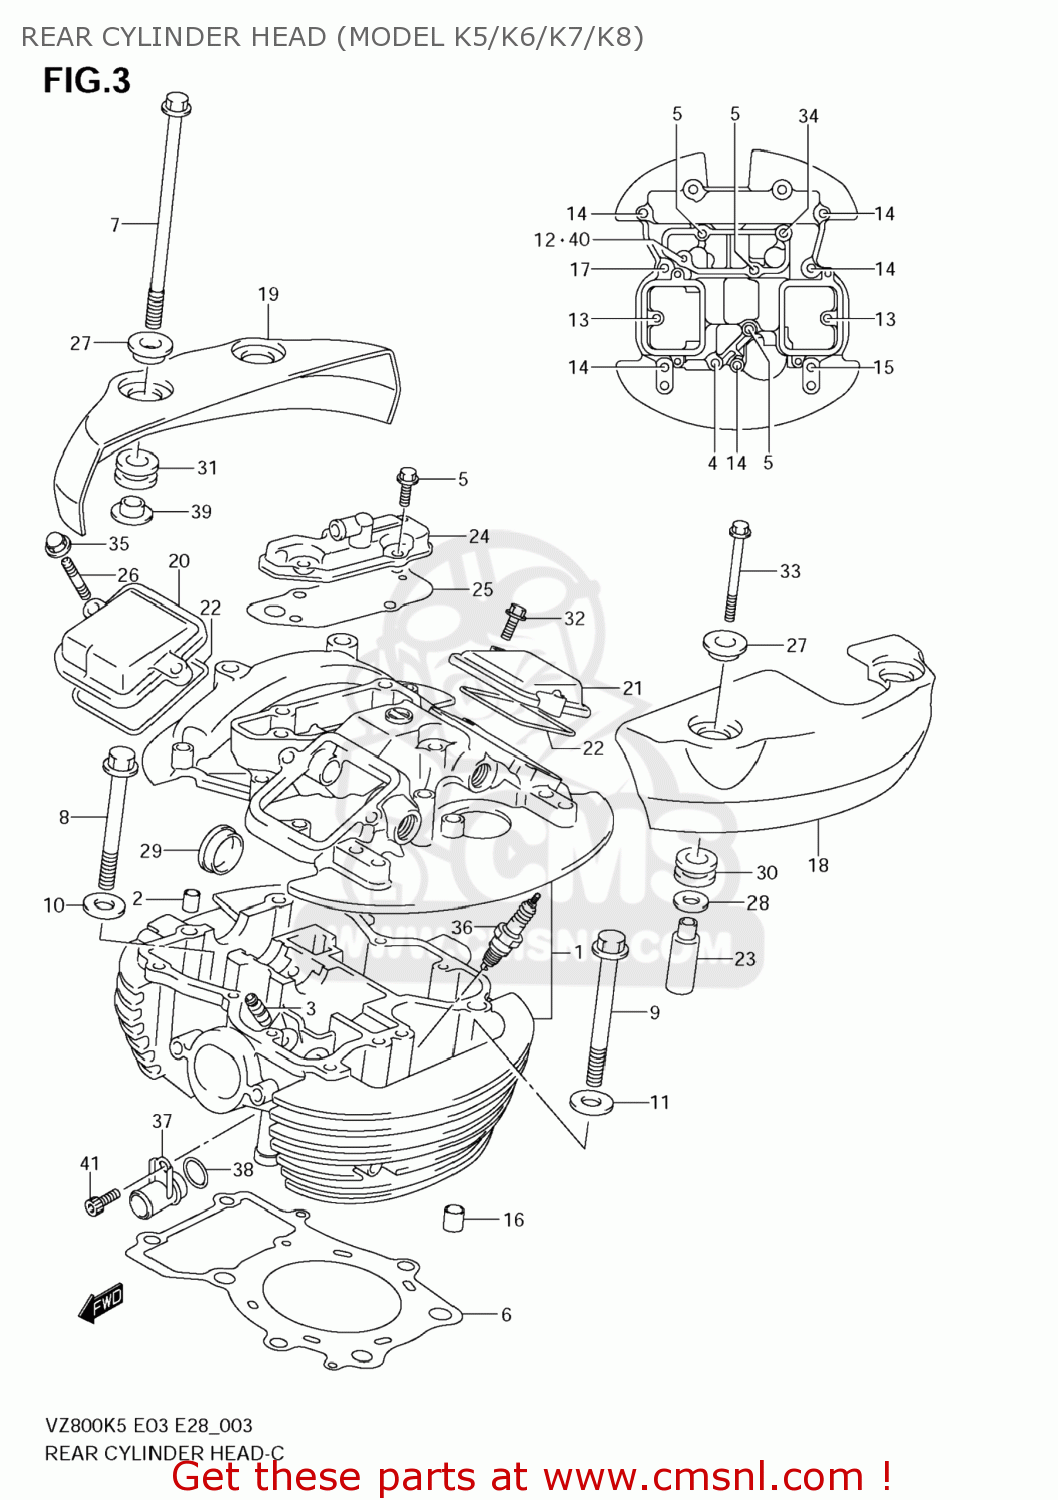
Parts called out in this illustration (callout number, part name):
1	HEAD ASSY,CYLINDER RR
2	PIN(8.4X11X14)
3	GUIDE,VALVE
4	BOLT(6X50)
5	BOLT(6X55)
6	GASKET,CYLINDER HEAD RR (NAS)
7	BOLT(8X250)
8	BOLT(10X155)
9	BOLT(10X165)
10	WASHER(8.5X24X1.6)
11	WASHER(10.5X22X2.3)
12	BOLT(6X55)
13	BOLT
14	BOLT
15	BOLT
16	PIN
17	BOLT
18	CAP,CYLINDER HEAD COVER RR,L
19	CAP,CYLINDER HEAD COVER RR
20	CAP,INSPECTION INTAKE
21	CAP,INSPECTION EXHAUST
22	GASKET,INSPECTION CAP (NAS)
23	SPACER,CYL HEAD COVER CAP NO.2
24	COVER,BREATHER
25	GASKET,BREATHER COVER (NAS)
26	BOLT,STUD
27	WASHER(6.5X18X1.6)
28	WASHER(9.5X20X1)
29	PLUG(OD:30)
30	CUSHION
31	CUSHION
32	BOLT
33	BOLT
34	BOLT
35	NUT
36	PLUG,SPARK(DPR7EA-9)
37	UNION,CYL HEAD JOINT
38	O RING(D:2.4,ID:15.8)
39	BUSH
40	GASKET(5.8X13X1.2) (NAS)
41	BOLT
